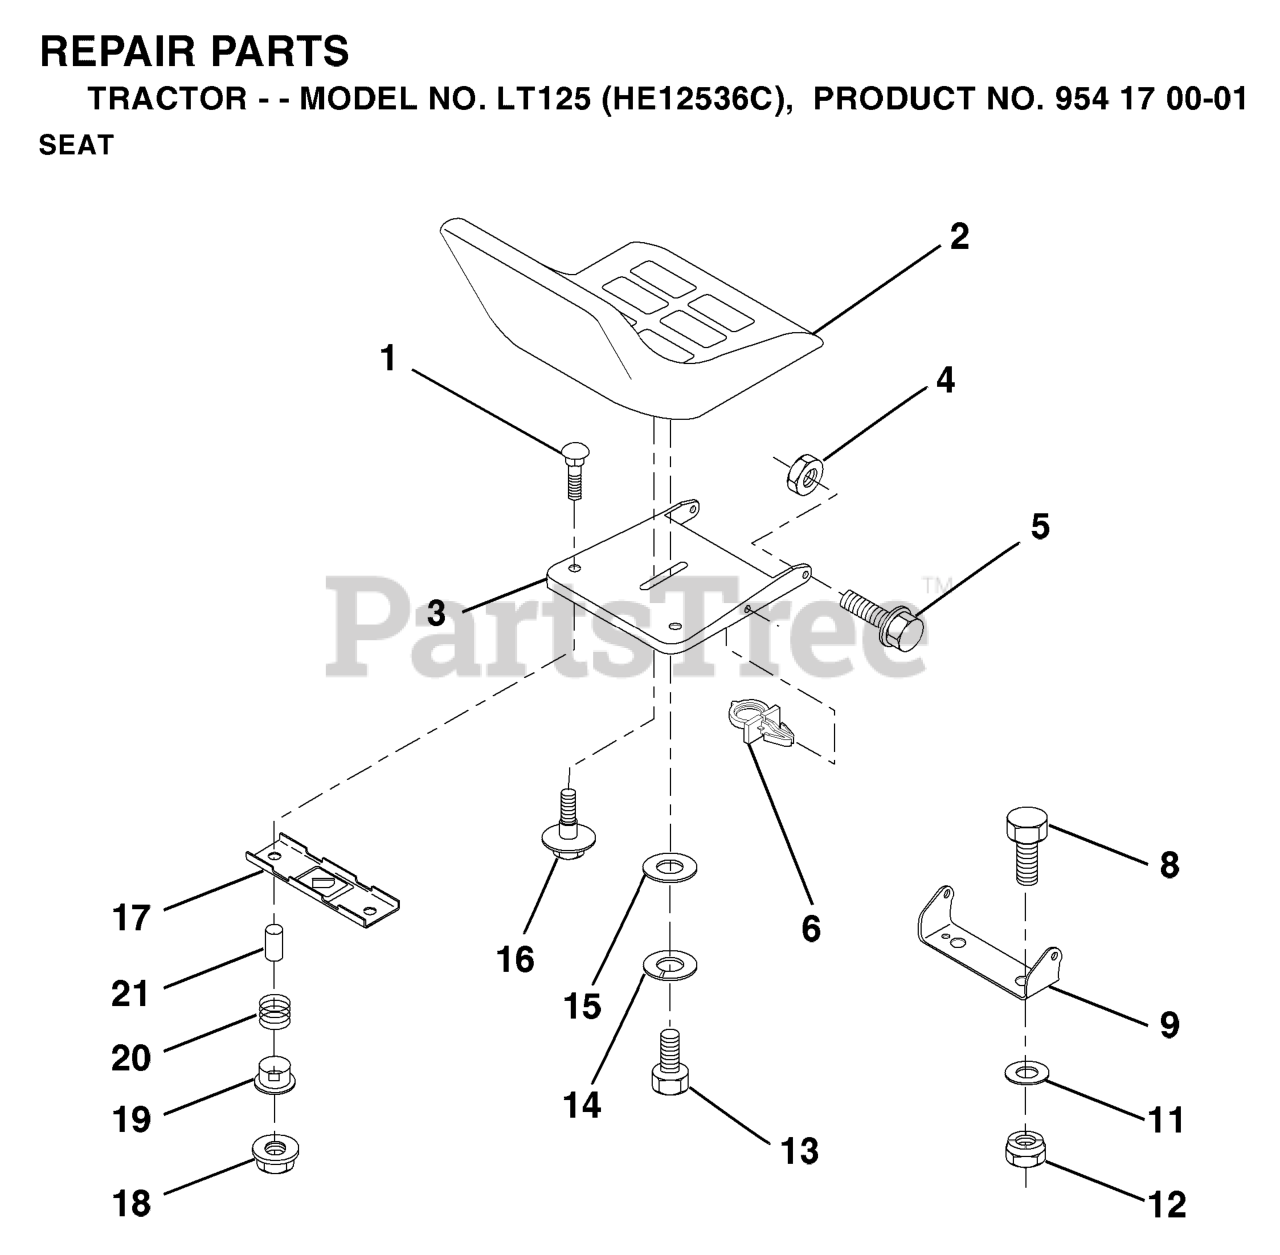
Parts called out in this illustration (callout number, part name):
1	BOLT.ROUND.HEAD.SQUARE.NECK
2	SEAT
3	PAN, SEAT
4	NUT.71038.31-18.HEX.NYLOCK
5	BOLT SHOULDER 5/16-18
8	BOLT
9	SEAT PIVOT BRKT
11	WASHER 12/32X2X10GA
12	NUT
13	BOLT
14	LOCKWASHER
16	BOLT,SHOULD
17	BRKT SWITCH
18	NUT T
21	SPACER SPLIT 28X.96
